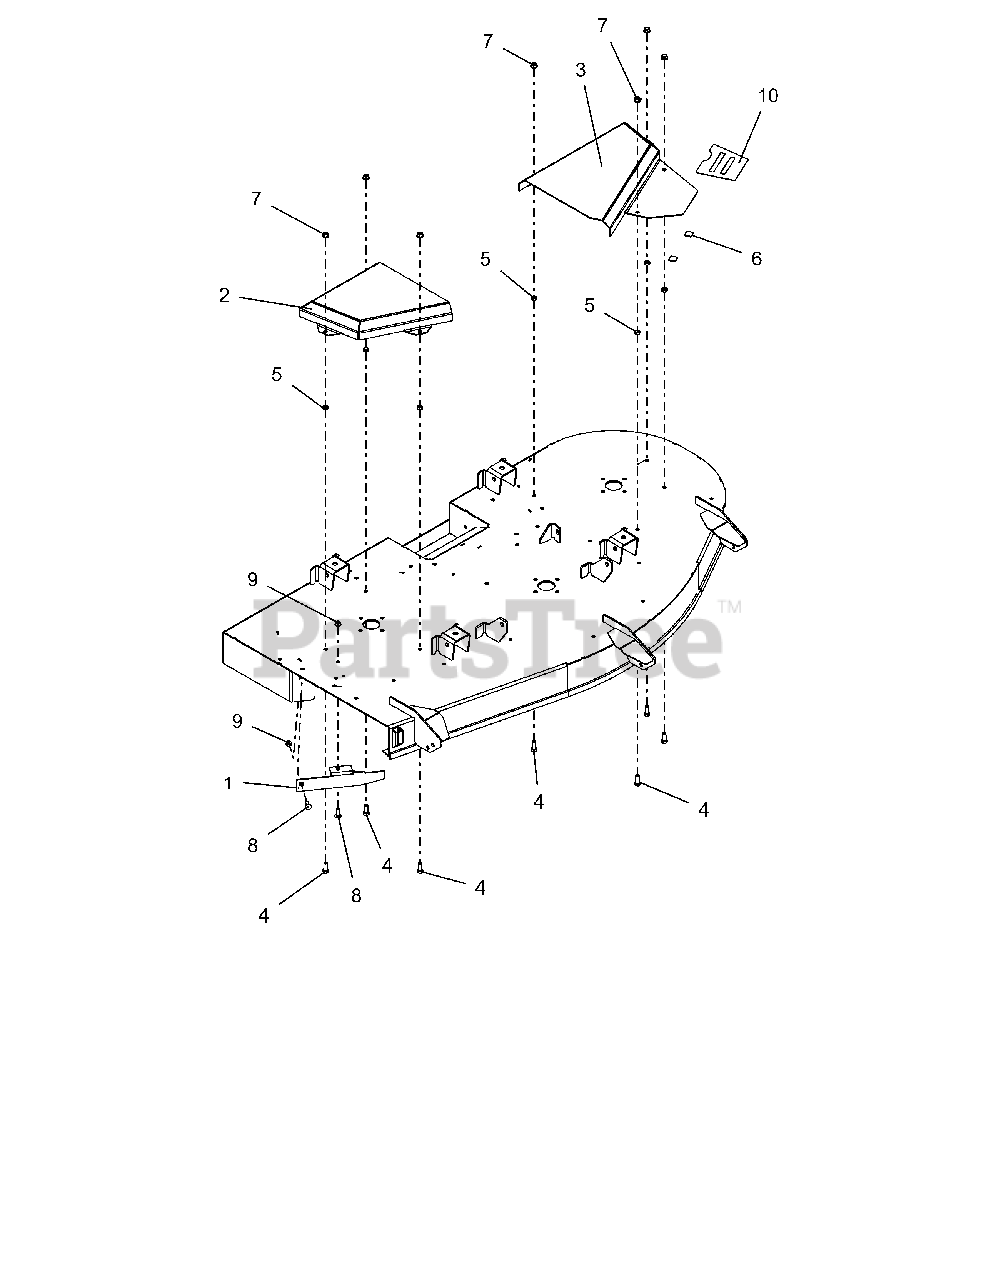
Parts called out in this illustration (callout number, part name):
1	BAFFLE, DISCHARGE 60"
2	COVER, BELT RH 60"
3	COVER, LH BELT 60
4	BLT,HEX .38-16X1.00 G5 ZCC
5	NUT-JAM .375-16 G2 ZCC
7	NUT-LK-TOP-FLG .38-16 ZC120
8	BLT,RHSN .31-18X1.00 G5 ZCC
9	NUT,NYL-FLG .31-18 GF ZCC
10	GRIP, TAPE 52-60 BELT COVER
